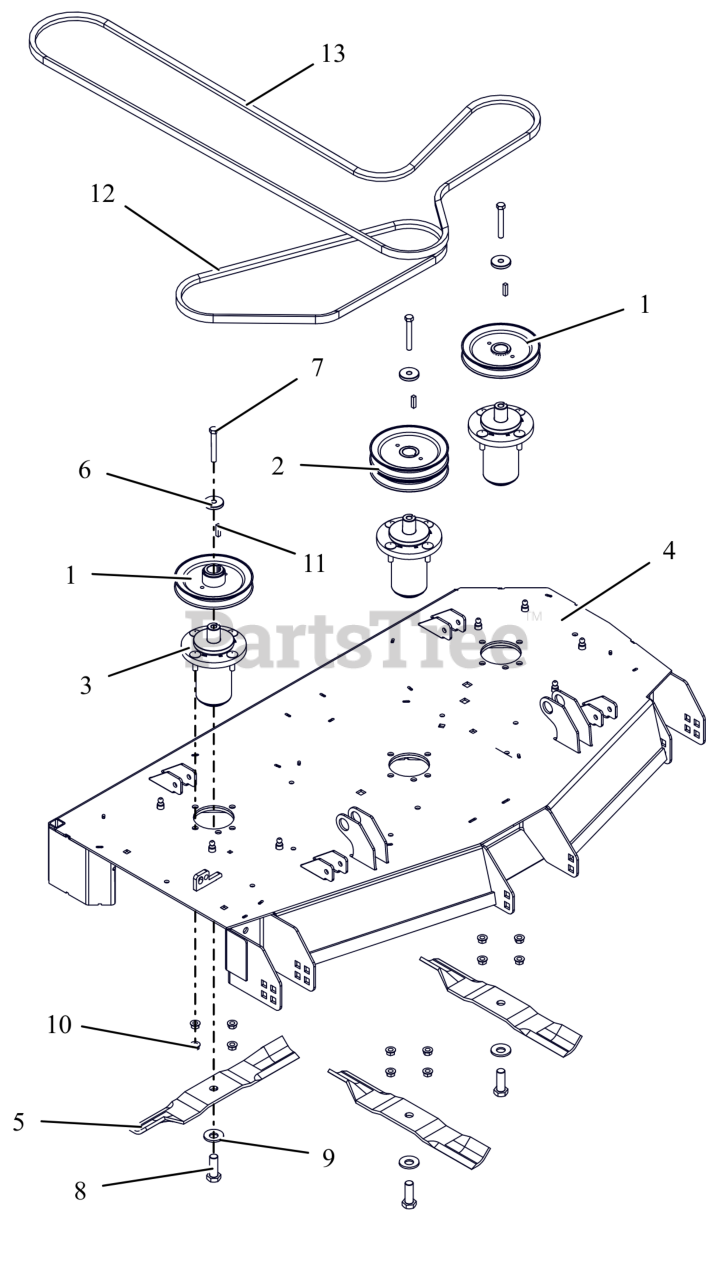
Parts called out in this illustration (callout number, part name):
1	PULLEY, SINGLE-1"ID X 6" OD
2	PULLEY, DOUBLE
3	ASM, MAINT FREE ALUM SPINDLE
4	KIT, DECK-48 W/DECALS 7GA XF3 RED
5	BLADE, 16.19" MOWER (HI-LIFT)
6	RETAINER, SHEAVE
7	BLT, HEX .38-16X2.75 G8 ZCC
8	BLT, HEX .62-18X1.75 G8 ZCC
9	WSHR-BLVL .669X1.535X.138
10	NUT-LK-CTR-FLG .375-16 GF ZCC
11	KEY, SQ .25X.25X1.00 RC 40-50
12	V-BELT, B-COGGED
13	V-BELT, HB SECTION
